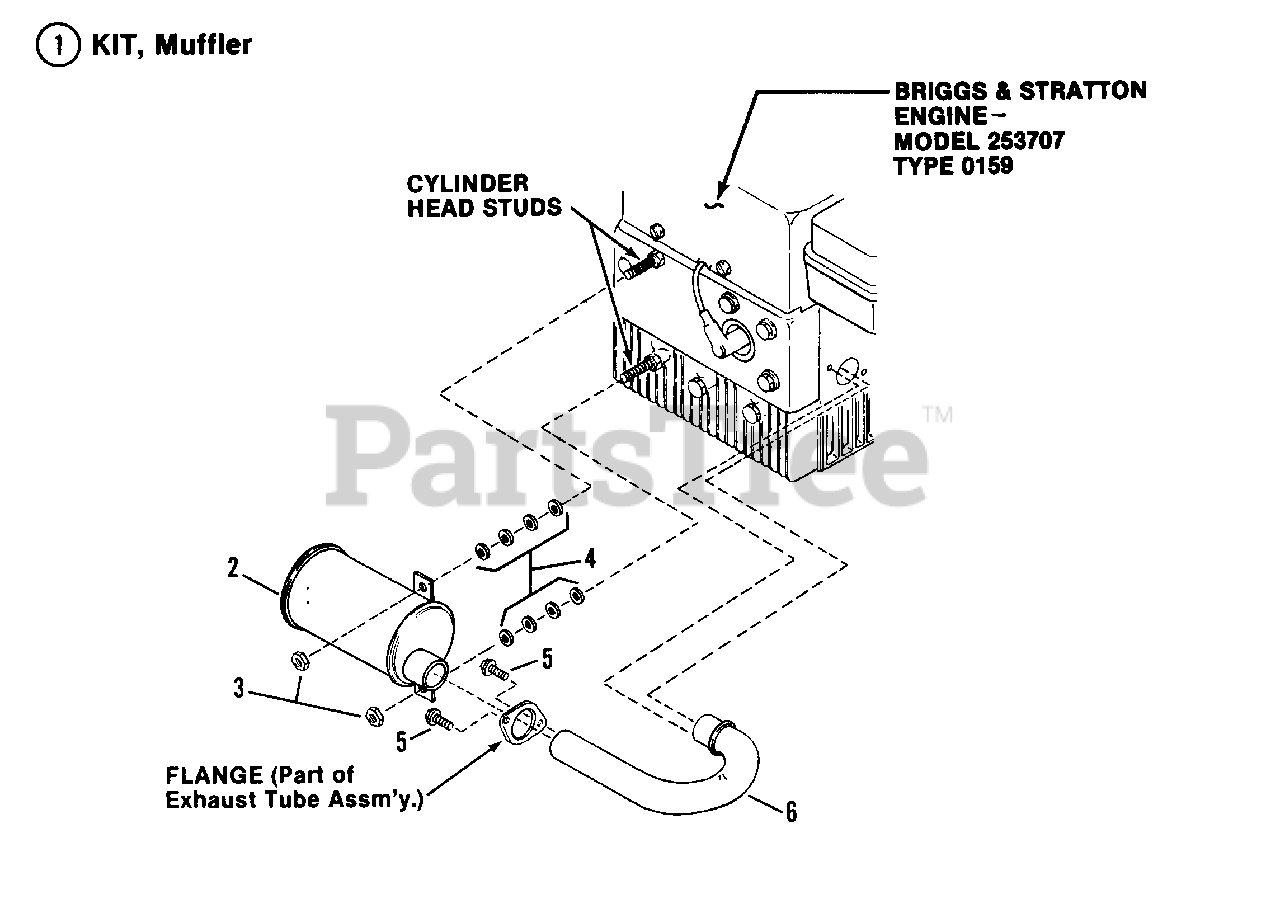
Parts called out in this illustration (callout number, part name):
1	KIT, Muffler
2	MUFFLER
3	NUT, 5/16-18 Hex
4	WASHER, 5/16 SAE
5	CAPSCREW, 5/16Cx3/4" Hex Head
6	TUBE, Exhaust
